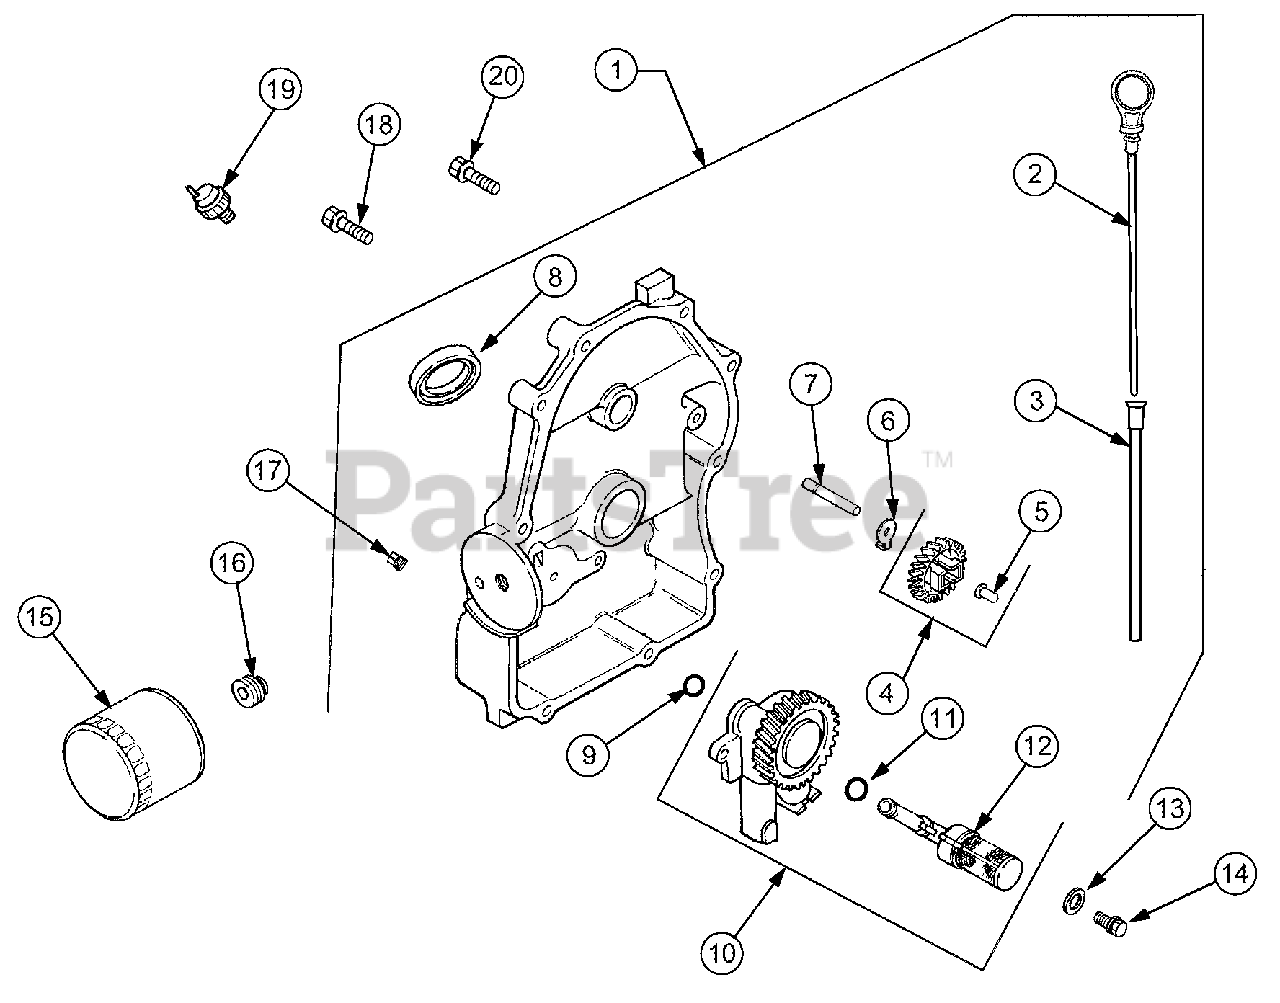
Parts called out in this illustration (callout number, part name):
1	Plate Assy, Closure
3	Tube, Dipstick
4	Kit, Governor Gear
5	Pin, Governor Regulating
6	Tab, Locking
7	Shaft, Governor Gear
8	Seal, Oil (PTO end)
10	Oil Pump Assy
11	O-Ring, Oil Pick-up
12	Pick-up, Oil
13	Washer, Plain
14	Screw, Hex Flange, M6 x 1.0 x 25
15	Filter, Oil
16	Nipple, Oil Filter
17	Plug, Pipe 1/8
18	Screw, Hex Flange, M8 x 1.25 x 45
19	Switch, Pressure
20	Screw, Hex Flange, M8 x 1.25 x 45
